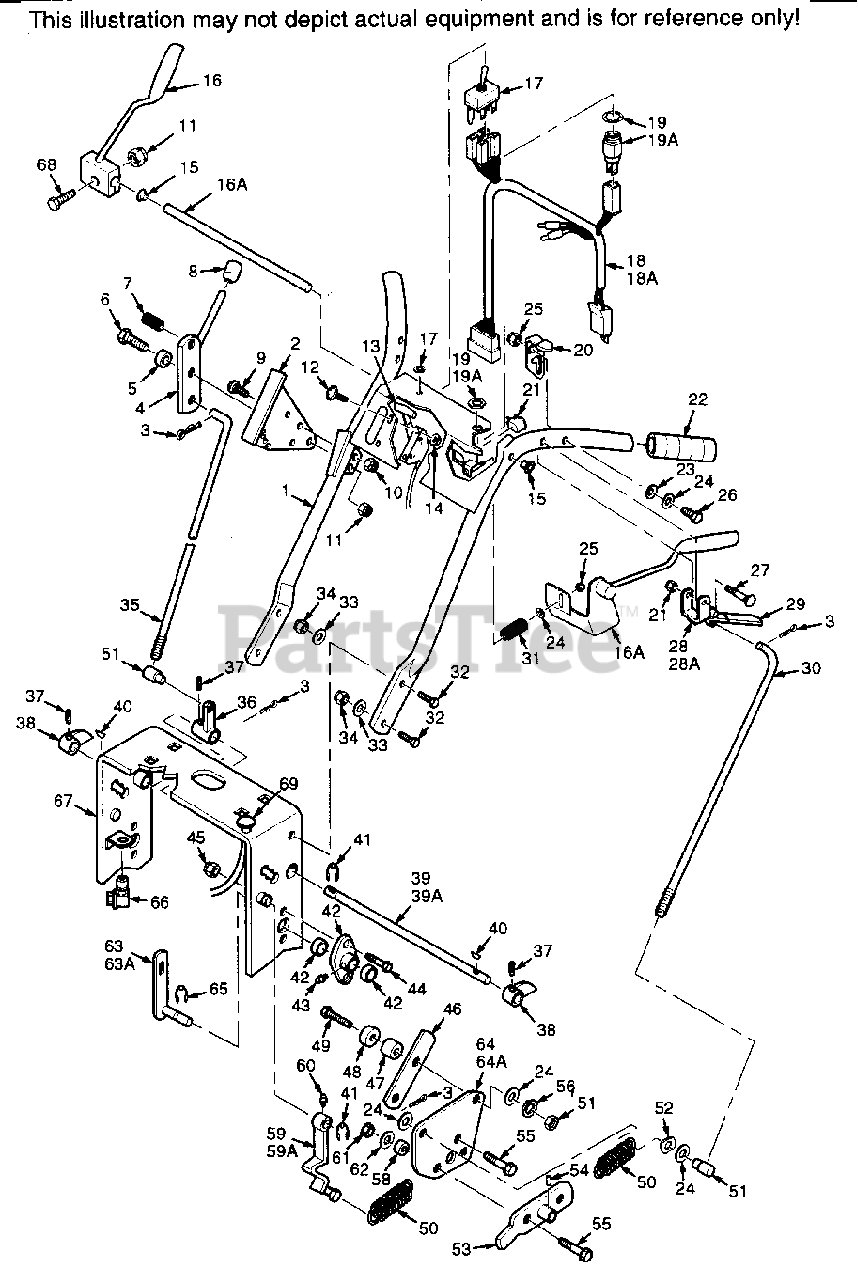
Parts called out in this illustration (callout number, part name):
1	UPPER HANDLE ASSY.(16" DECK)
2	QUADRANT, SPEED CONTROL
3	HAIR PIN, SMALL
4	LEVER, SPEED ADJ.
5	BUSHING, SPEED ADJ. LEVER
6	BOLT, 5/16-18 X 1-1/2, HH.
7	BALL PLUNGER
8	KNOB, SPEED ADJ.
9	CAPSCREW, 1/4-20 X 3/4 FHHS
10	NUT, 1/4-20, ELASTIC STOP
11	NUT, 5/16-18, ELASTIC STOP
12	SCREW, # 10-32 X 1/2 PW HD
13	THROTTLE CONTROL
14	NUT, # 10-32, SERR. FL. HH
15	BUSHING
16	HANDLE, OPER PRES., RH
17	SWITCH, ELET CLUTCH ENGAGEMENT(INCL. NUT)
18	WIRE HARNESS, MANUAL START MODELS
19	KEYSWITCH, MANUAL START MODELS(INCLUDES
21	SWITCH, NEUTRAL INTERLOCK
22	GRIP
23	WASHER, CURVED SPRING
25	NUT, 5/16-18, LOCKNUT, ELASTIC
26	BOLT, 5/16-18 X 2, HH
27	BOLT, 5/16-18 X 2 1/2, CARRIAGE
28	LEVER, STEERING CONTROL, RH
28A	LEVER, STEERING CONTROL, LH
29	GRIP, STEERING CONTROL LEVER
30	ROD, STEERING CONTROL
31	SPRING, HANDLE RETURN
34	NUT, 3/8-16, SERR. FL. HH
36	BELLCRANK, SPEED CONTROL(INCLUDES SETSCREW)
37	SETSCREW, 1/4-28 X 1/4 H. SOCK., KNURLED CUP
38	CAM, SPEED CONTROL(INCLUDES SETSCREW)
39	JACKSHAFT, SPEED CONTROL(FOR 16" DECK)
39A	JACKSHAFT, SPEED CONTROL(FOR 20" DECK)
40	KEY, 1/8 X 1/2, WOODRUFF # 3
41	RING, RETAINING 5/8, TRU ARC
42	PIVOT, PUMP CONTROL SHAFT(INCL. BUSHINGS/
43	ZERK, GREASE, 1/4-28, SELF TAP.
44	CAPSCREW, 5/16-18 X 1, SERR. FL. HH
45	NUT, 5/16-18, ELASTIC
46	BAR, SPEED CONTROLX
47	SPACER, SPEED CONTROL BEARING
48	BEARING, SPEED CONTROL BELLCRANK
49	BOLT, 5/16-18 X 1 3/4, FULL THREAD, HH
50	SPRING RETURN
51	SWIVEL JOINT, STEERING ROD
52	WAVE WASHER
53	HANDLE, NEUTRAL ADJ.
54	DRIVE PIN, 5/16 X 1 1/4 TYPE U
55	CAPSCREW, 5/16-18 X 3/4 SERR. FL. HH
57	NUT, 5/16-18, HH
58	BEARINGS, BALL, NEUTRAL RETURN
59	CAM, NEUTRAL(RH)(INCLUDES GREASE ZERK)
59A	CAM NEUTRAL(LH)(INCLUDES GREASE ZERK)
61	NUT, 3/8-16, SERR. FL.
63	SHAFT, PUMP CONTROL,(LH)
63A	SHAFT, PUMP CONTROL,(RH)
64	BELLCRANK, PUMP CONTROL(LH)
64A	BELLCRANK, PUMP CONTROL(RG)
65	RETAINING RING, 1/2 EXT.
66	SWITCH, NEUTRAL START
67	DECK, ENGINE(SEE ENGINE DECK COMPONENT)
68	BOLT, 5/16-18 X 1 1/4, HH
69	CHOKE CONTROL
